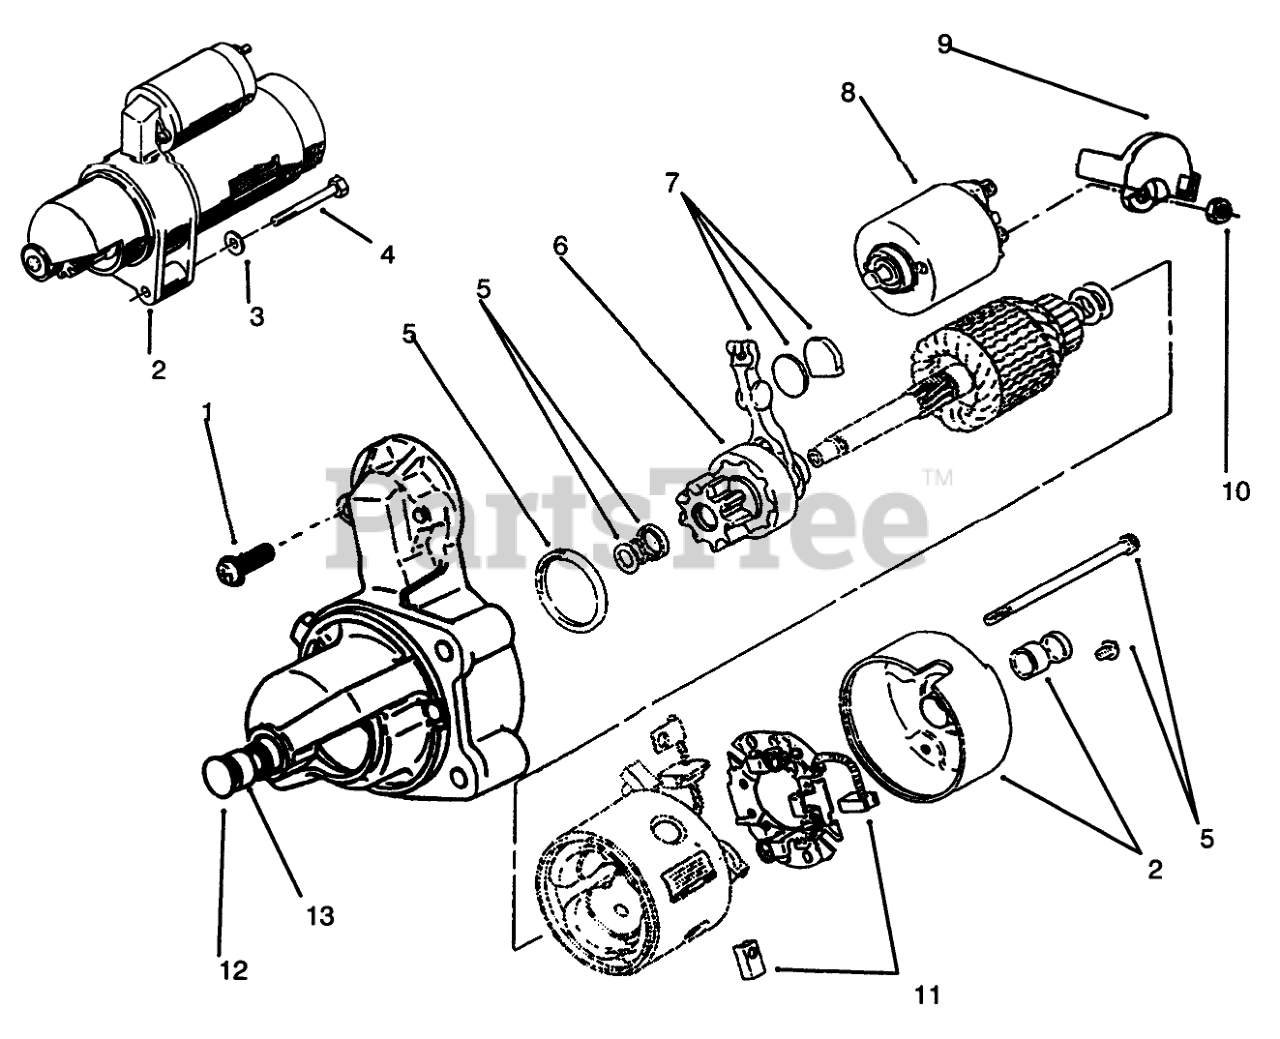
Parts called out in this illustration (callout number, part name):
1	Starter Hdwr Kit (Incl. Solenoid Screws 2] Brush Holder Screws 2], Thru Bolts2], Armature Shims 2], Pinion Stop Collar, & Pinion Retaining Ring)
2	STARTER
3	WASHER
4	SCREW
5	DUST-SEAL KIT
6	Clutch-Starter (Incl. Pinion Gear w/Clutch)
7	Kit-Starter Shift Lever (Incl. Shift Lever, Wear Plate & Rubber Plug)
8	Kit-Starter Solenoid (Incl. Solenoid, Spring, & Plunger)
9	Cap-Starter Solenoid
10	O-RING
11	Kit-Starter Brush (Incl. Positive Brush 2] & Negative Brush w/Pigtail)
12	Kit-Bushing (Incl. Front Bushing & Rear Cap w/Bushing)
13	Holder-Starter Brush (Incl. Brush Holder w/Negative Brush)
